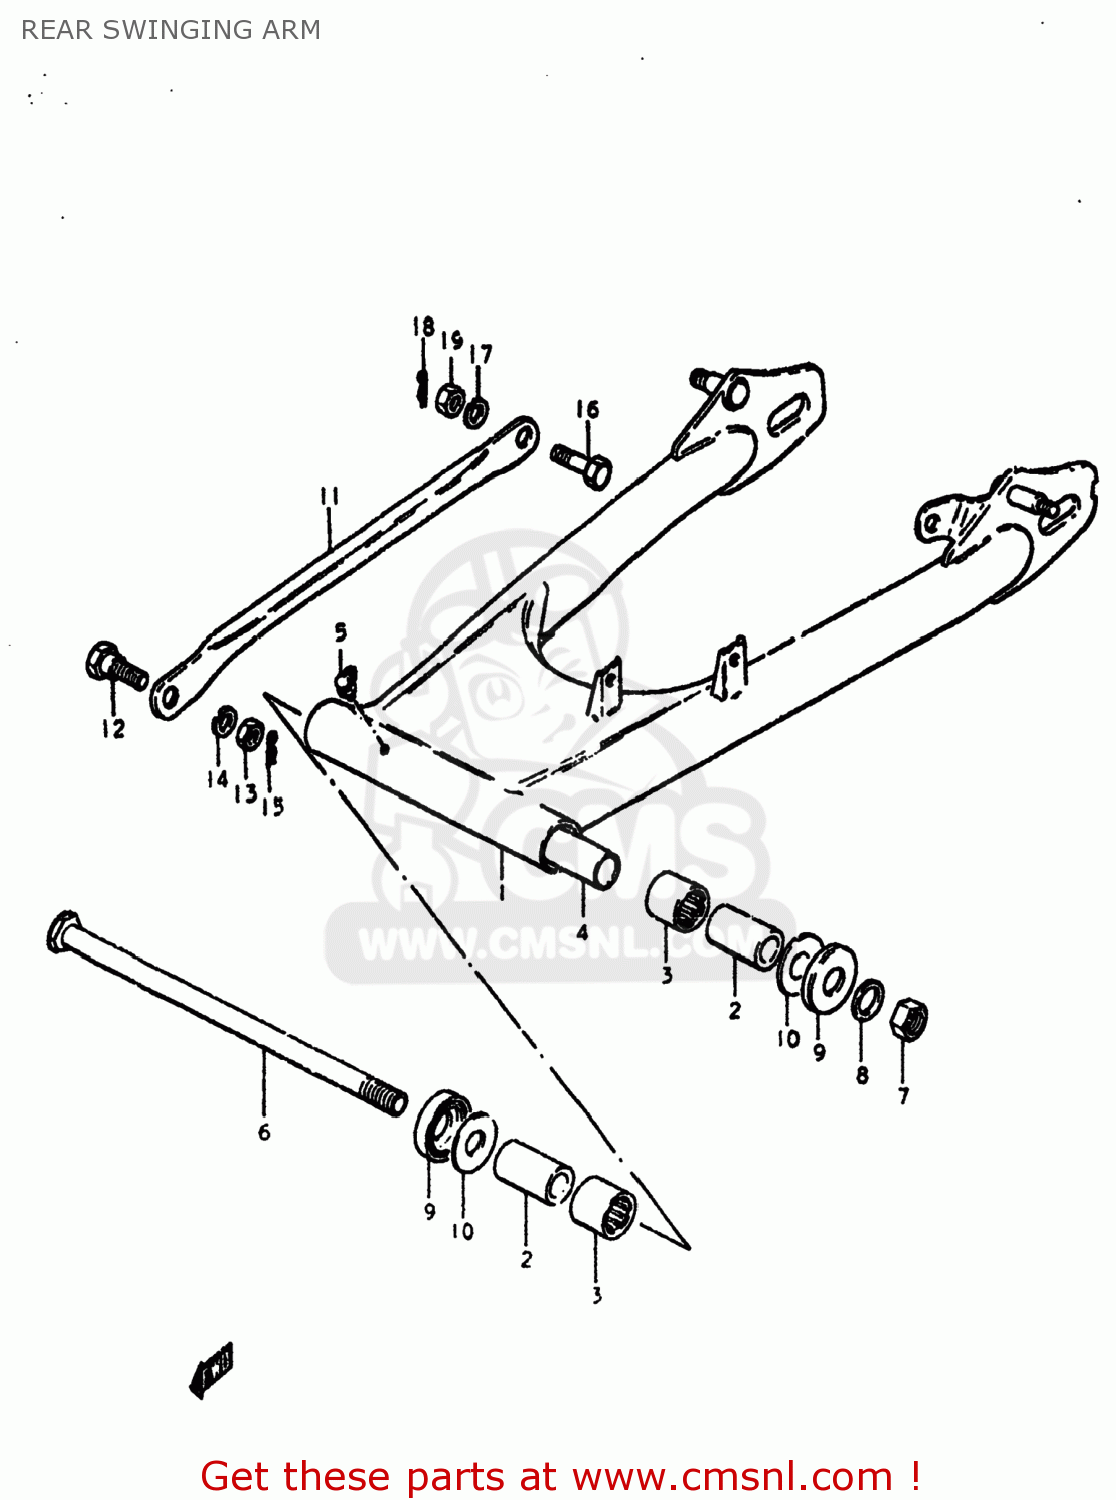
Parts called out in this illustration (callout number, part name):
1	SWING ARM ASSEMBLY,REAR
2	SPACER,RR SWGARM PIVOT
3	BEARING(22X29X30)
4	SPACER,SWINGINGARM CTR
5	NIPPLE,GREASE
6	SHAFT,REAR SWING ARM
7	NUT 14MM
8	WASHER
9	CVR,RR SWGARM DUST SEAL(OD:40)
10	WASHER(14.2X34X1)
11	TORQUE LINK,REAR
12	BOLT(10X24.5)
13	NUT
14	LOCK WASHER
15	CLIP
16	BOLT(10X31)
17	LOCK WASHER
18	CLIP
19	NUT
